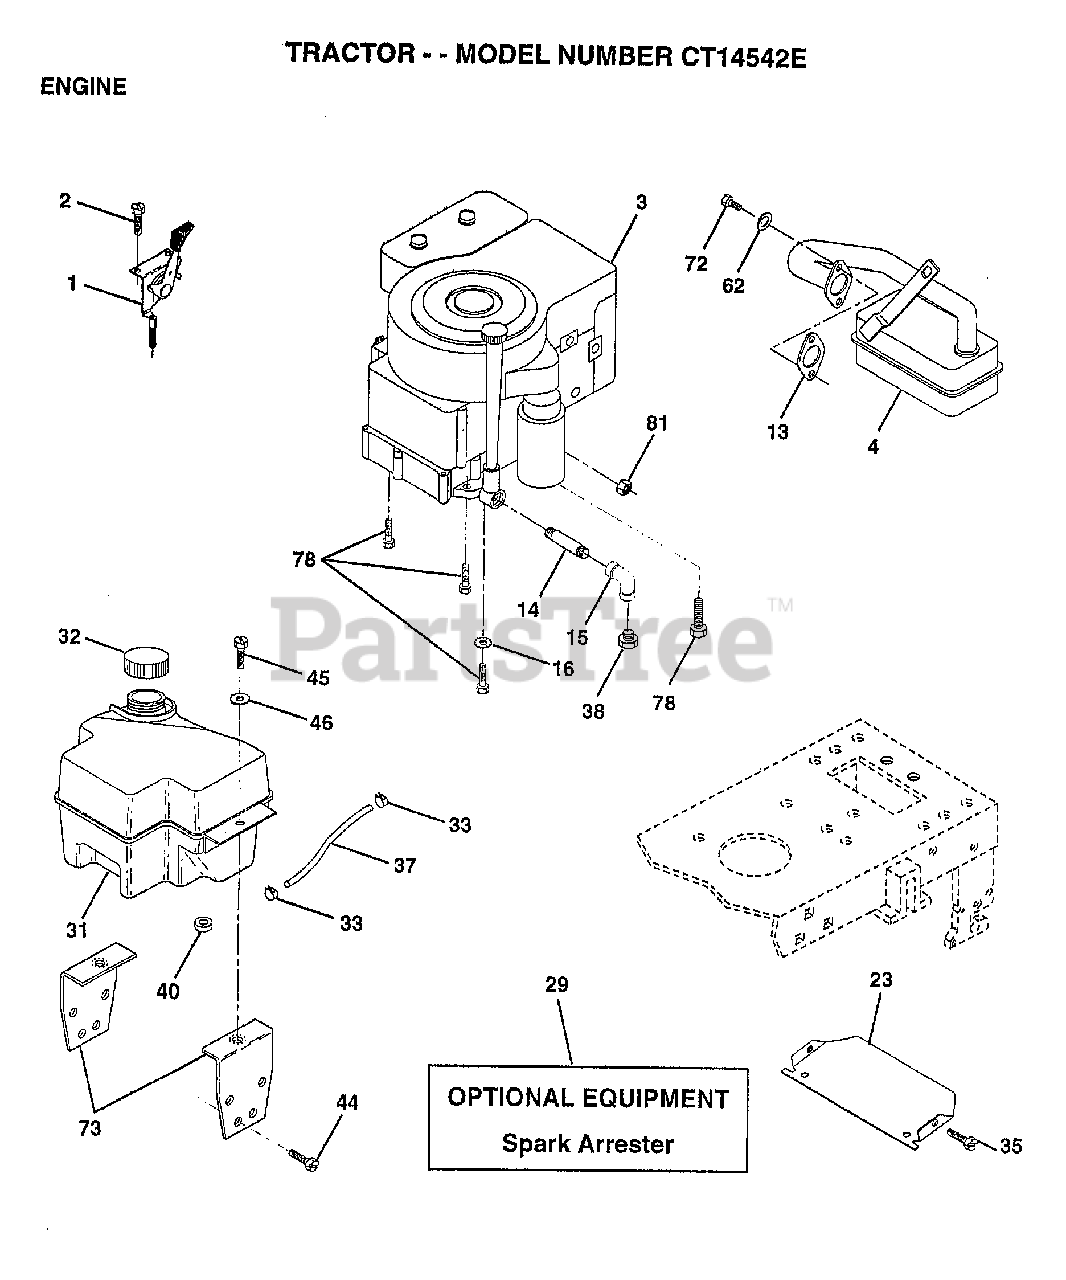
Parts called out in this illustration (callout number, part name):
1	CONTROL.THTL.19.6
2	SCREW LT
4	MUFFLER
13	GASKET ENG 1 313 LD TIN PLATED
14	PIPE NIPPLE
15	ELBOW
16	LOCKWASHER
23	SHIELD-HEAT
32	CAP ASM FUEL
33	HOSE CLAMP
35	SCREW
37	LINE FUEL
44	SCREW
45	SCREW HEX CRT
46	WASHER
62	LOCKWASHER
72	SCREW
73	BRACKET.SUPT.TANK
78	SCREW
81	NUT
